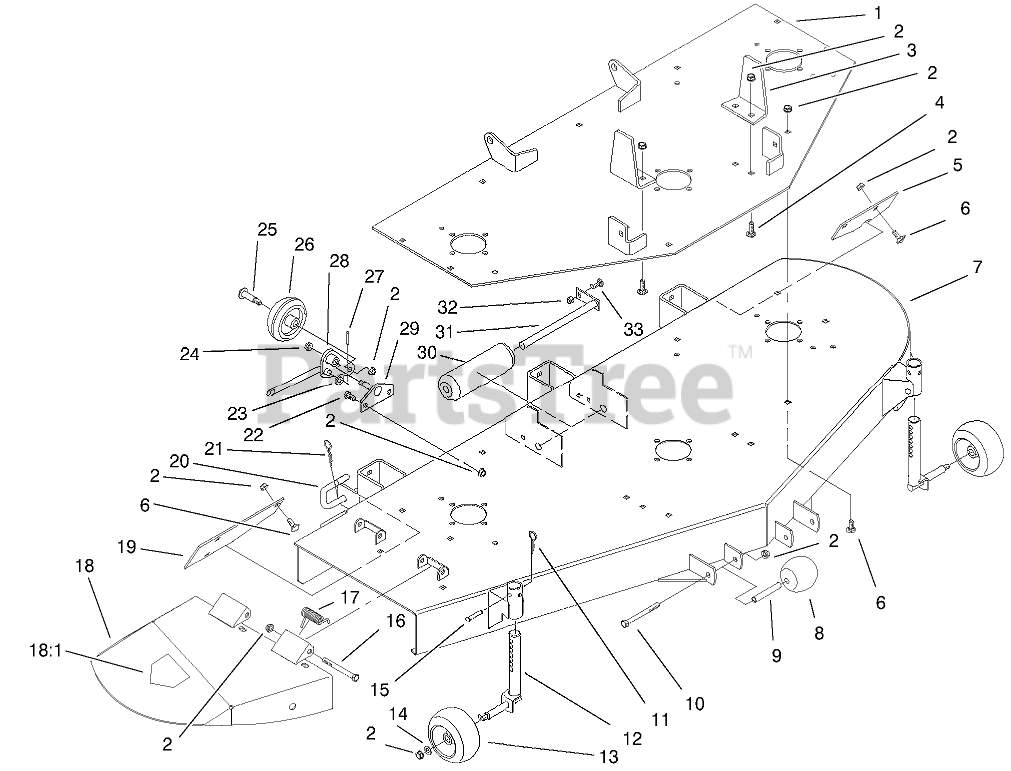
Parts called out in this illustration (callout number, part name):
2	NUT-LOCK, NI
3	BRACKET-GUIDE
4	BOLT-CARR
5	PLATE-WEAR LH
6	BOLT-CARR
7	DECK
8	ROLLER
9	TUBE-SPACER, WHEEL
10	SCREW-HH
11	PIN-HAIR
12	GAGE WHEEL SUPPORT
13	WHEEL-GAGE
14	WASHER-FLAT
15	PIN-CLEVIS
16	SCREW-HH
17	SPRING
18	CHUTE/DECAL ASM
18:1	DECAL-DANGER
19	PLATE-WEAR RH
20	ROD - WHEEL PIVOT
21	PIN-COTTER, HAIR
22	SCREW-HH
23	WASHER-FLAT
24	LOCKNUT-FLANGE
25	SCREW-SHOULDER, HWH
26	WHEEL-GAGE
27	PIN-COTTER
28	PIVOT ARM
29	Pivot Plate
30	ROLLER-ANTI SCALP
31	ROLLER-SHAFT
32	NUT-LOCK, NI
33	BOLT-CARR
